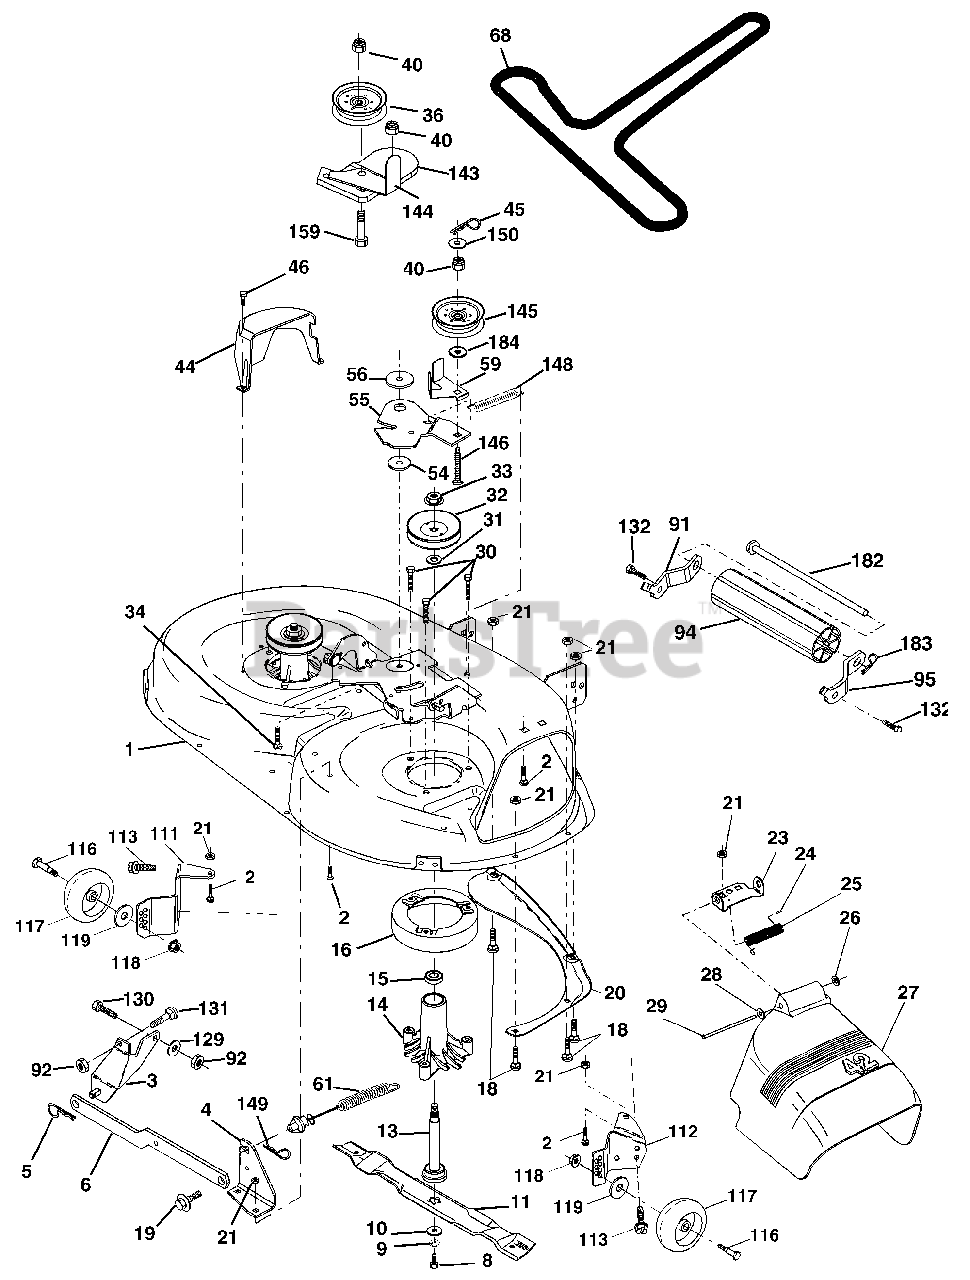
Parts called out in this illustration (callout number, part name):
1	Housing Asm Mower 42"94 T-Path
2	Bolt Rdhd Sqnk 5/16-18 Unc x 3/4
3	Bracket Asm Fr Sway Bar 38/42
4	Bracket Asm Deck 42"sway Bar
5	Retainer Spring
6	Bar Sway Deck
8	Bolt 3/8-24 x 1 25 Gr8 Patched
9	Washer Lock Hvy 3/8 Unplated
10	Washer Hard Blade Mower Vented
11	Blade Mower High Lift"
13	Shaft Asm W/lower Bearing
14	Housing Mandrel Vented(machd)
15	Bearing Ball Mandrel
16	Stripper Mower
18	Bolt Carr 5/16-18 x 5/8
19	Bolt Shoulder
20	Baffle Vortex 42
21	Nut Crown Lock 5/16-18
23	Bracket Deflector Mower 42"
24	Cap Sleeve 80x 112 Blk Mower
25	Spring Torsion Deflector 2 52
26	Nut Push Phos & Oil
27	Shield Deflector
28	Washer 11/32 x 5/8 x 16 Ga
29	Rod Hinge 42"6 75 Wlg
30	Screw Thd Rolling Hex
31	Washer Spacer
32	Pulley Mandrel
33	Nut 9/16top Lock Flng Cntr
34	Bolt Carr. Sh 3/8-16 x 1-1/2 Gr.5
36	Pulley Idler Flat 3 060
40	Nut Lock Flange 3/8-16 Unc
44	Guard Mandrel LH Black
45	Retainer Spring
46	Screw Thdrol 1/4-20 x 5/8
54	Washer Hardened
55	Arm Idler 42" mower LT/YT
56	Spacer Retainer Mower
61	Spring Ext. Elect
91	Bracket Asm Noseroller LH
92	Nut Lock Hex w/ins. 3/8-16 Unc
94	Roller Nose 38 & 42
95	Bracket Asm Noseroller RH
111	Bracket Gauge Wheel Lh
112	Bracket Gauge Wheel Rh
113	Bolt 5/16-18 Hex Whs. Hd. LCKSERR
116	Bolt Shoulder
118	Nut Centerlock 3/8-16 Unc
119	Washer 3/8 x 7/8 x 14 Ga.
129	Washer 13/32 x 13/16 x 12 Ga.
130	Bolt Fin Hex 3/8-16 Unc x 1 Gr. 5
131	Bolt Rdhd Sqnk 3/8-16 Unc x1
132	Screw 3/8-16 x .75
143	Bracket Arm Idler
144	Keeper Belt
145	Pulley Idler Flat
146	Bolt Carriage Idler
148	Spring Return Idler
149	Retainer Spring Yellow
150	Washer 9/32 x 3/4 x 16
159	Bolt RDHD SQN 3/8-16 x 1-3/4
182	Rod Roller Nose Standard
183	Retainer Spring
184	Washer 13/32 x 7/8 x 10 Ga.
